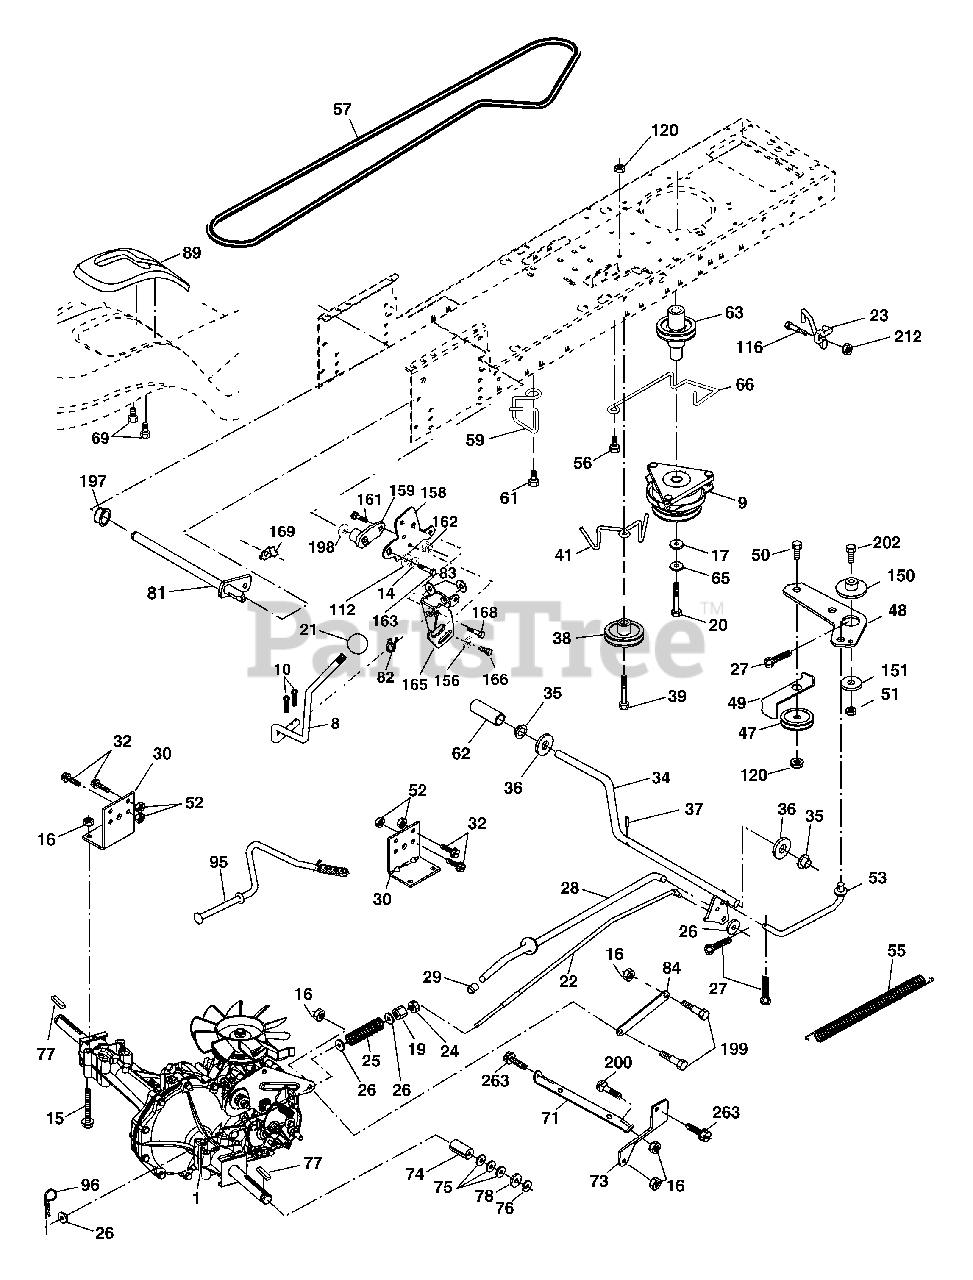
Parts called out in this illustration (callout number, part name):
8	Rod Shift Fender
9	Clutch Electric
10	Pin Cotter 1/8 x 1 CAD
14	Washer Lock Hvy Helical
15	Bolt Hex Flghd 5/16-18 Gr. 5
16	Nut Lock Hex W/Ins. 5/16-18 unc
17	Washer 1-1/2 OD x 15/32 ID x .250
19	Nut Lock Hex W/Wsh 3/8-16 unc
20	Bolt, Hex 7/16-20 x Gr. 5-1.5
22	Rod, Brake Hydro
23	Bracket Asm. Anti-Rot CVX
24	Locknut
25	Spring, Brake Rod
26	Washer
27	Pin Cotter 1/8 x 3/4 CAD.
28	Rod, Parking Brake
29	Cap, Parking Brake
30	Bracket, Transaxle
32	Bolt Hex Hd 5/16-18 unc x 3/4
34	Shaft, Foot Pedal Nibbed
35	Bearing, Nylon
36	Washer
37	Pin, Roll
38	Pulley, Idler, Flat Composite
39	Bolt 3/8-16 x 2-3/4 Gr. 5
41	Keeper, Belt Idler Fool-Proof
47	Pulley, Idler, V-Groove
48	Bellcrank Clutch Grnd Drv Stl
49	Retainer, Belt
50	Bolt Carr. SH 3/8-16 x 1-1/2 Gr. 5
52	Nut Crown Lock 5/16-18
53	Link, Clutch
55	Spring, Return, Clutch
56	Screw 3/8-16 x 1-1/4
57	V-Belt, Ground Drive
59	Keeper, Center Span
61	Screw 3/8-16 x .875
62	Cover, Pedal
63	Pulley, Engine
65	Washer
66	Keeper Belt Engine Hydro
69	Screw Hex Wsh Hi-Lo 1/4-1/2 unc
71	Strap Torque Lh Hydro
73	Strap Torque Rh Hydro
74	Spacer, Axle
75	Washer 25/32 x 1-1/4 x 16 Ga.
77	Key, Square
78	Washer 25/32 x 1-5/8 x 16 Ga.
81	Shaft Asm. Cross Hydro
82	Spring Torsion T/A
83	Washer 17/32 x 3/4 x 16 Ga.
84	Link Transaxle
89	Console, Shift
95	Control Asm. Bypass Hydro
96	Retainer Spring 1" Zinc/Cad
112	Washer 9/32 x 3/4 x 10 Ga.
116	Bolt RDHD SQNK 3/8-16 unc x 1
120	Nut Lock 3/8-16
150	Spacer Retainer
151	Washer 13/32 x 2 x 10 Ga.
156	Washer Srrted 5/16 ID x 1.125
158	Bracket Shift Mount
159	Hub Shift
161	Bolt Rdhd Sqnk 1/4-20 x 3/4 Gr. 5
162	Nut Crownlock 1/4-20 unc
163	Bolt Hex Fin 1/4-20 unc x 1 Gr. 5
165	Bracket Pivot Lever
166	Screw 5/16-18 x 5/8
168	Bolt Shoulder 5/16-18 x .561
169	Plate Fastening Lt\
197	Nyliner Snap-In 5/8" ID
198	Washer Nyliner 7/8 ID x .105
199	Bolt Shoulder 5/16-18 unc
200	Bolt Rdhd Sq Neck 5/16-18 unc x 1
202	Bolt 3/8-16 x 1-3/4 Gr. 5
212	Nut Hexflange Lock
263	Screw Hexwsh Thdr 3/8-16 x 3/4
